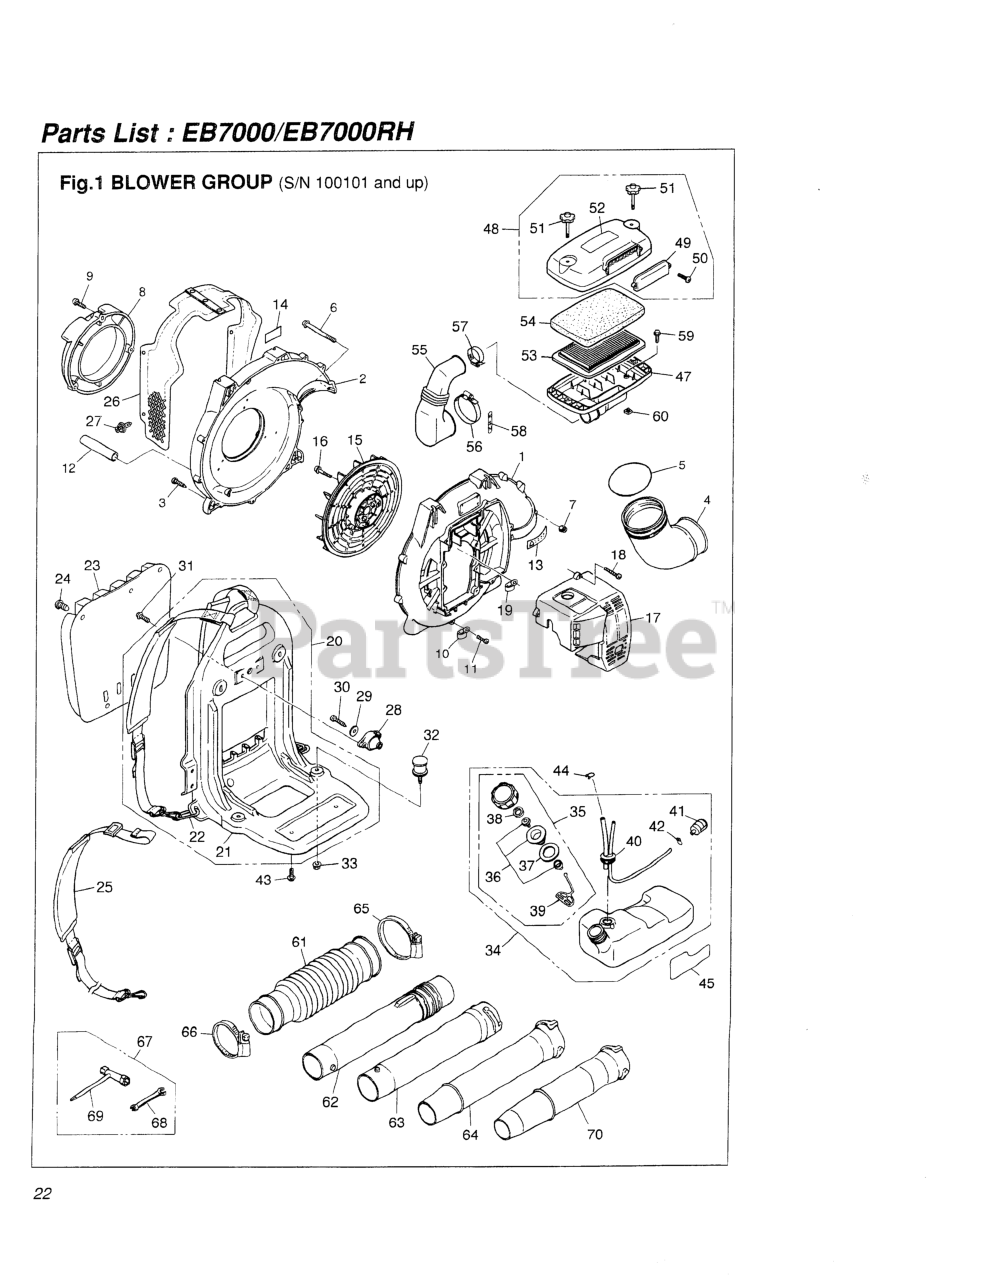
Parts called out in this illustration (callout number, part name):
1	CASE, VOLUTE
2	COVER, VOLUTE (USE-31212)
3	SCREW, M5 X 25
5	O-RING
6	SCREW, M5 X 70
7	NUT (B)
8	COVER, INLET
9	SCREW, M5 X 25
10	CLAMP
12	TUBE (RPLS. 07270-01507)
13	LABEL, CAUTION (RPLS -31910)
14	LABEL, NET
15	FAN
16	BOLT (RPLS 3405-12211)
17	COVER, ENGINE (RPLS -31611)
18	SCREW, M5 X 25
19	CLAMP
22	RING (REPLACES -21120)
23	PAD (RPLS -21310)
24	CLIP (RPLS 3490-21320)
25	BAND ASSY (RPLS 2750- )
26	NET COMPLETE
27	CLIP
28	DAMPER, UPPER
29	WASHER
30	SCREW
31	BOLT, M5 X 16 (RPLS -32540)
32	DAMPER, LOWER
33	NUT, M6
34	TANK ASSY (RPLS. -85100)
35	CAP ASSY (RPLS -85201)
36	HOLDER (REPLACES -85230)
37	PACKING
38	FILTER
39	STOPPER
40	PIPE COMPLETE
41	FILTER ASSY
42	CLIP (REPLACES 2841-31280)
43	SCREW, M5 x 12
44	CLIP
48	COVER ASSEMBLY
49	COVER
50	SCREW, M5 X 25
51	BOLT, KNOB
52	LABEL, CLEANER (EB7000)
53	ELEMENT (PAPER)
55	HOSE
56	BAND
57	BAND
58	LABEL, CHOKE
60	NUT
61	HOSE (RPLS 2750-51110)
62	JOINT, SWIVEL (USE 51201)
64	PIPE, END
65	CLAMP (RPLS 3490- )
66	CLAMP (RPLS 3050-13230)
67	TOOL SET
68	SPANNER, 8 X 10 (RPLS 2540- )
69	WRENCH, SOCKET
70	KIT, NOZZLE (USE 2756-51221)
